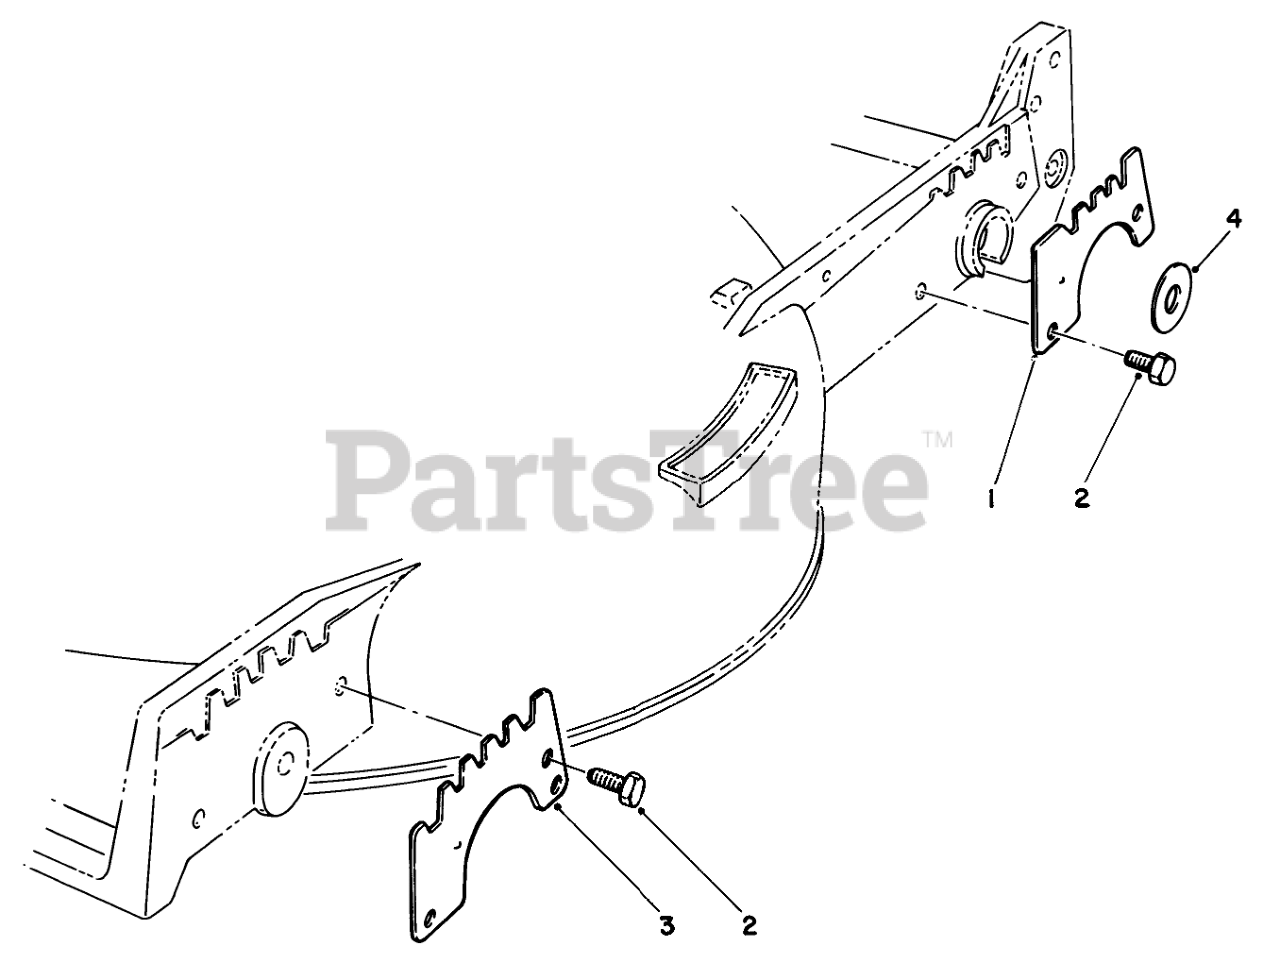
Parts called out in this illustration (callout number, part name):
1	WEAR PLATE,REAR
2	SCREW-HWH
3	WEAR PLATE
4	PIVOT WASHER
